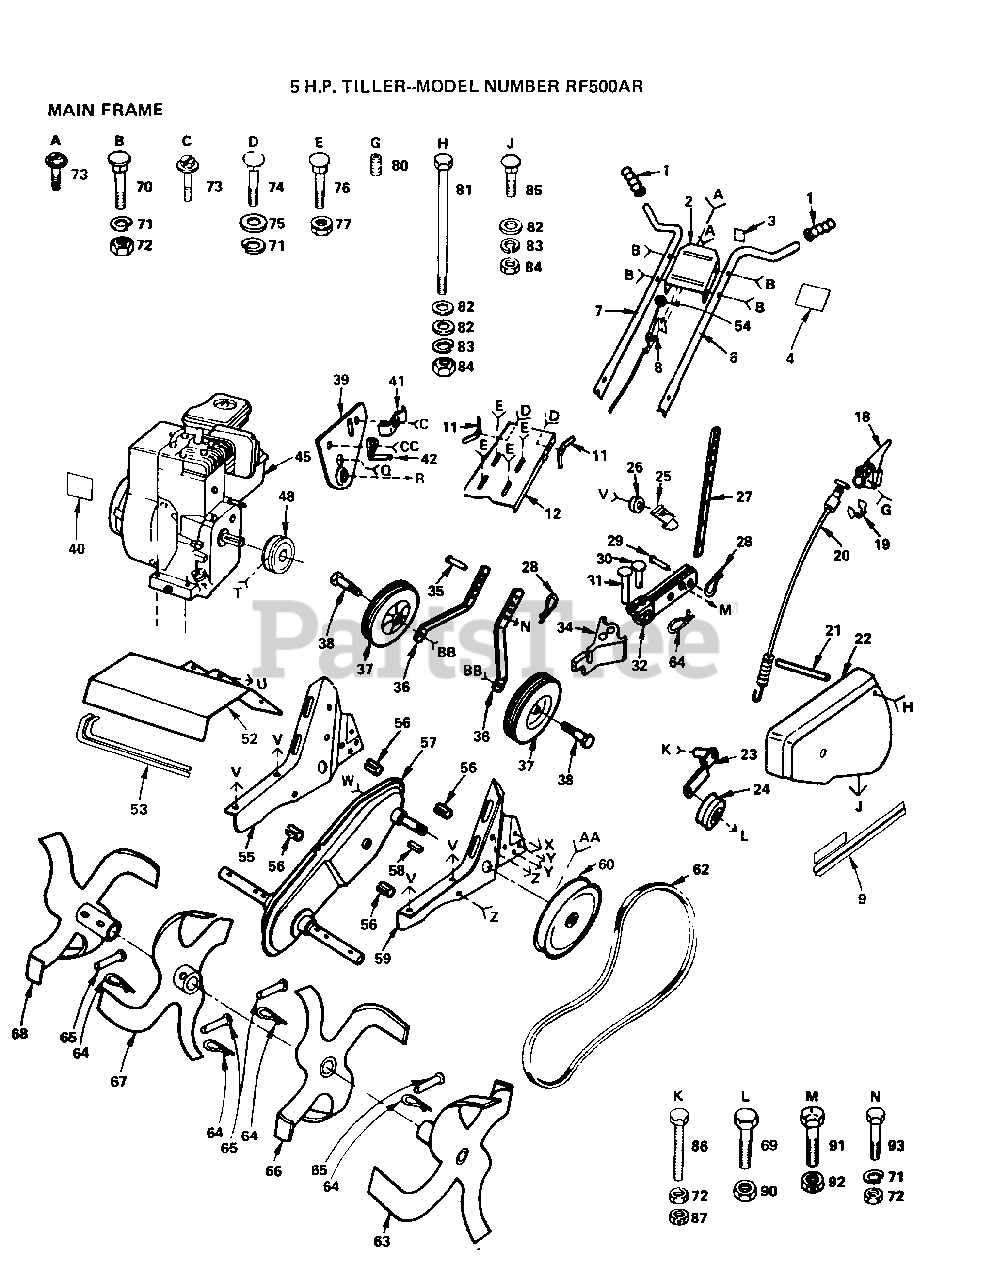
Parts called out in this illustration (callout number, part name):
2	BRACKET - HANDLE
8	THROTTLE CONT TI
9	DECAL - BELT GUARD
18	CONTROL LEVER TI
19	E-RING
20	CABLE CLUTCH T
21	SPLIT SPACER
25	STAKE SPRING TI
28	SPRING.RETAINER
31	RIVET
35	DRILLED RIVET RT
37	WHEEL TI
38	BOLT M
41	CONDIUT CLIP T
53	DECAL - TINE SHIELD
56	SPLIT SPACER RT
58	KEY T
60	TRANS SHEAVE RT
62	V BELT STD
63	TINE WELDMENT TI
64	RETAINER.SPRING
65	RIVET.PAN HD.1.75
68	TINE WELDMENT TI
71	LOCKWASHER
72	NUT.HEX.5/16-18
73	SCREW TI
74	BOLT
75	WASHER
77	NUT
80	SCREW
82	WASHER
83	LOCKWASHER
85	BOLT
90	NUT
92	GRIPCO NUT
